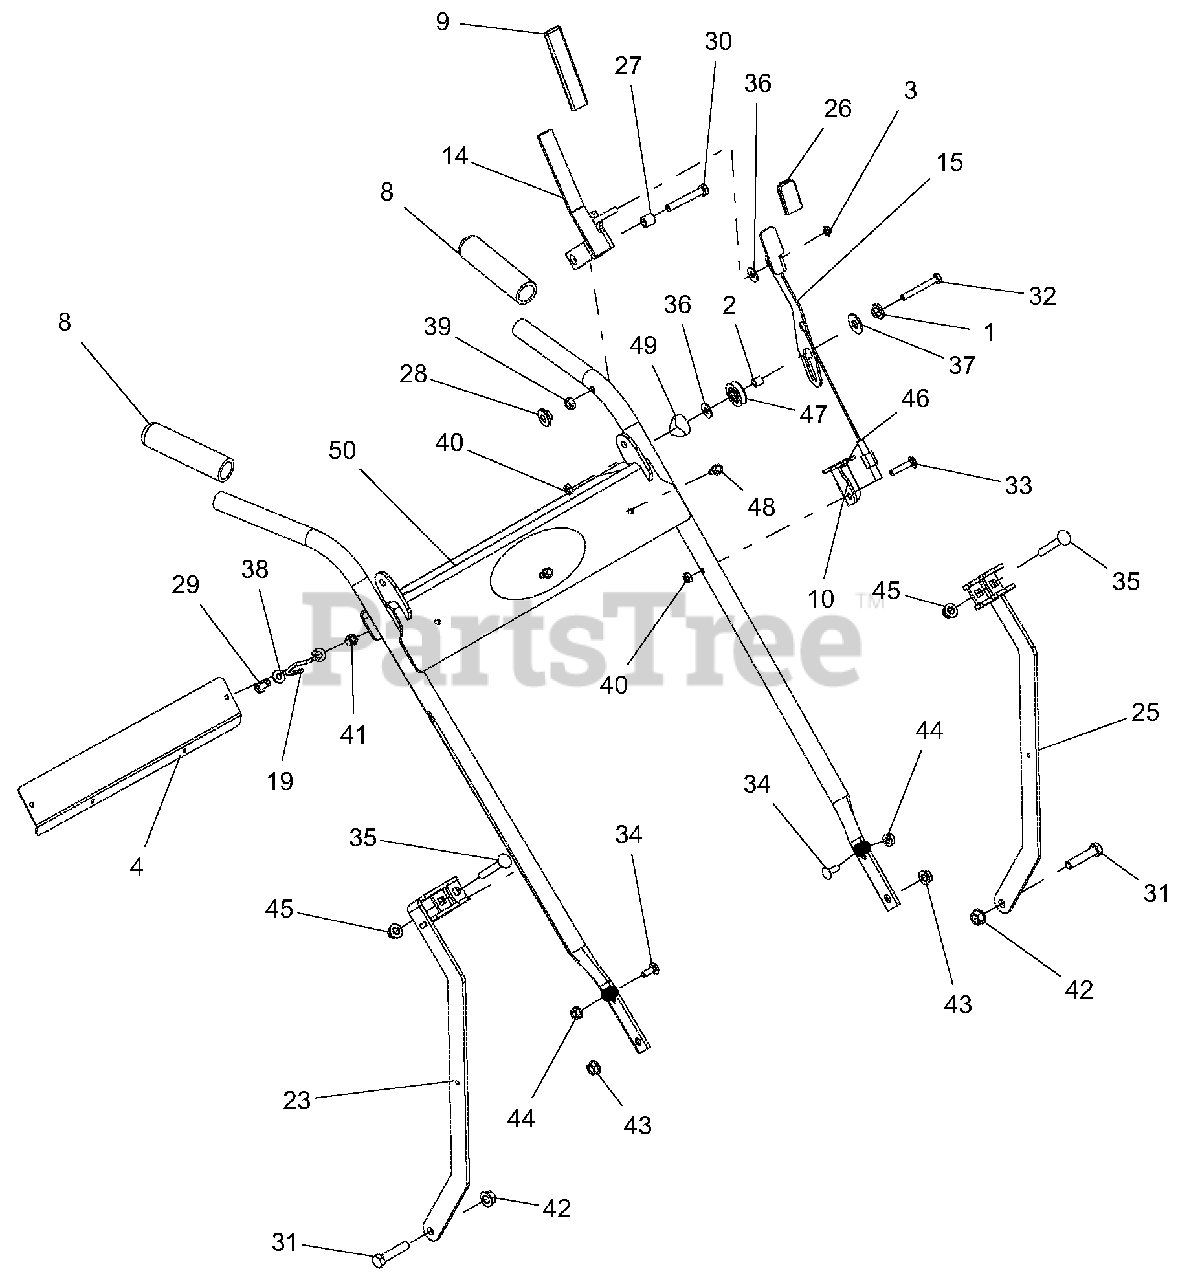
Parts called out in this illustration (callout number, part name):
1	BSHG, FLG .266X.42X.150 PM
2	TUBE-SPACER, .280X.375X.375
3	PUSH NUT, .25
4	BACKER, GRAVELY
8	GRIP, BLACK 7/8ID
9	GRIP MZR/MOMENT SP 7/8X3/4X4
10	MOUNT, UPPER PTO CABLE
14	WMT-PTO LEVER, HWM
15	WMT-HWM PTO INTERLOCK
19	GUIDE - PULLCORD
23	WLDMT, RH HANDLEBAR SUPPORT
25	WLDMT, LH HANDLEBAR SUPPORT
26	GRIP, THUMB LATCH
27	BSHG-SLV .334X.500X.50
28	BSHG-FLG .32X.500X.344X.880
29	@BLT-HEX .25-20X.75 GR5 YWZC
30	@BLT-HEX .31-18X2.00 GR5 YWZC
31	@BLT-HEX .38-16X1.75 GR5 YWZC
32	@BLT-HEX .25-20X2.00 GR5 YWZC
33	@BLT-RDHDSQNK .25-20X1.25 G5YZ
34	@BLT-RDHDSQNK .25-20X.75 G5YZ
35	@BLT-RDHDSQNK .31-18X2.25 G5YZ
36	@WSHR-FL-STL.312X.734X.065 YWZ
37	@WSHR-FL-STL.438X1.00X.083 YWZ
38	@WSHR-FL-STL.281X.62X.065 YWZC
39	@NUT-LK-CTR .31-18 YWZC
40	NUT-JAM-NYL .250-20 W/INSERTYZ
41	@NUT-LK-NYL .250-20 YWZC
42	@NUT-LK-TOP-FLG .38-16 YWZC
43	@NUT-LK-TOP-FLG .31-18 YWZC
44	@NUT-LK-TOP-FLG .25-20 YWZC
45	@NUT-LK-NYL-FLG .31-18 YWZC
46	CABLE, WAW PTO
47	PULLEY, CABLE
48	SCR-TAP .25-20X.50 HWH TR YWZ
49	SPACER, HANDLEBAR
50	HANDLEBAR,BRUSH SP W/ DECAL
